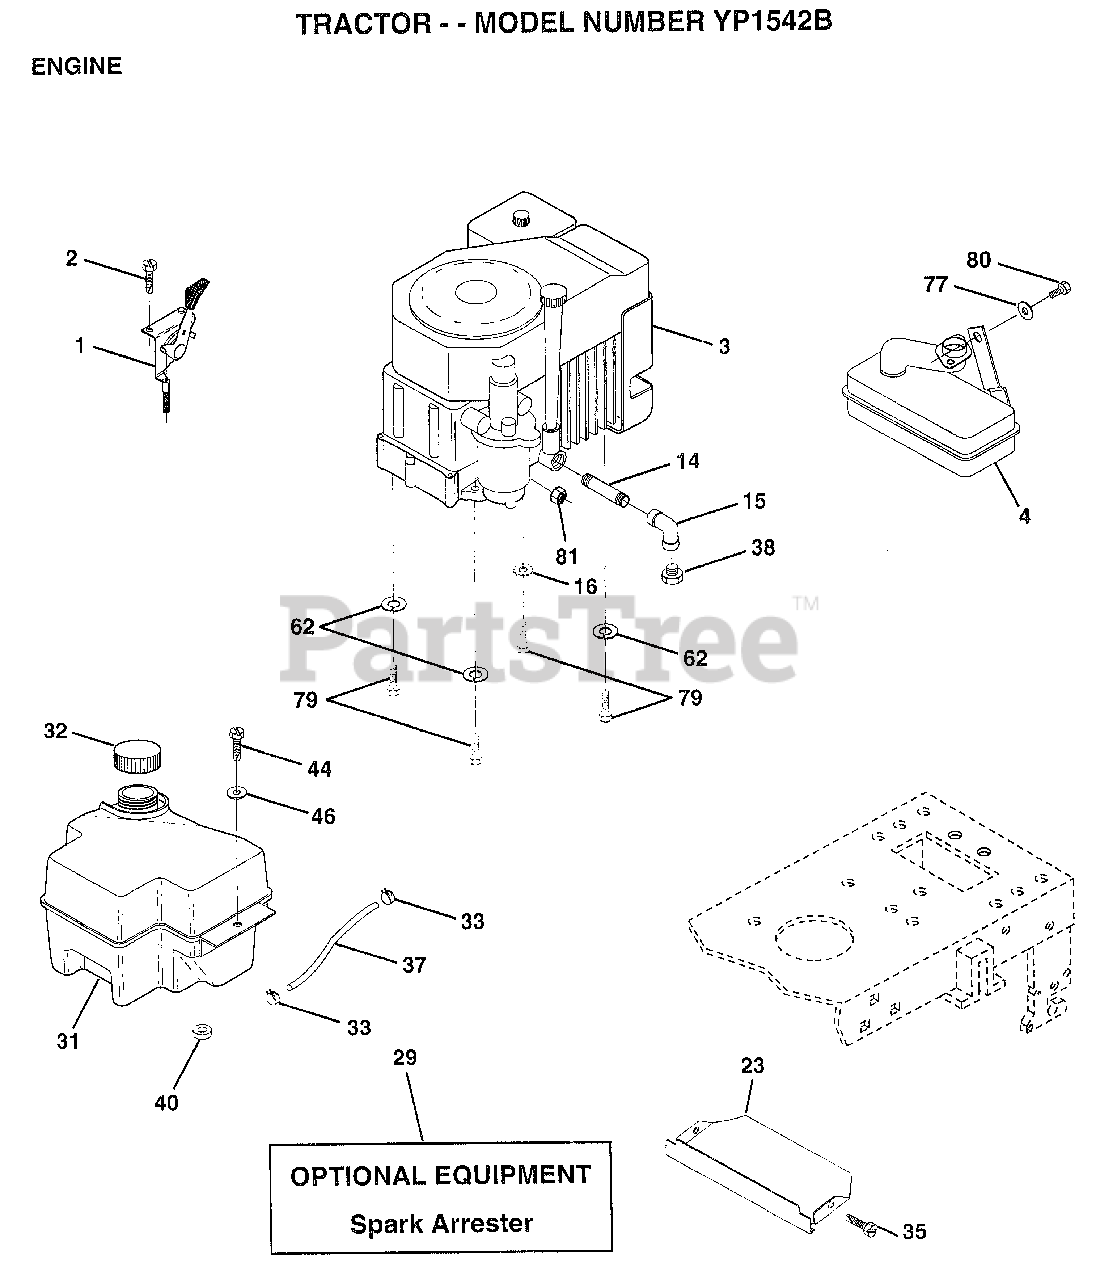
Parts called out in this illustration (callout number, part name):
1	CONTROL.THROTTLE/CHOKE
2	SCREW LT
4	MUFFLER.LT.12.5
14	PIPE NIPPLE
15	ELBOW
16	LOCKWASHER.5/16.E
23	SHIELD BRN/DBR GUARD
31	TANK.FUEL.FRONT.
32	CAP ASM FUEL
33	HOSE CLAMP
35	SCREW
37	LINE FUEL
44	SCREW HEX CRT
46	WASHER
62	LOCKWASHER
80	BOLT
81	NUT
101	NUT FLANGE M8-125
